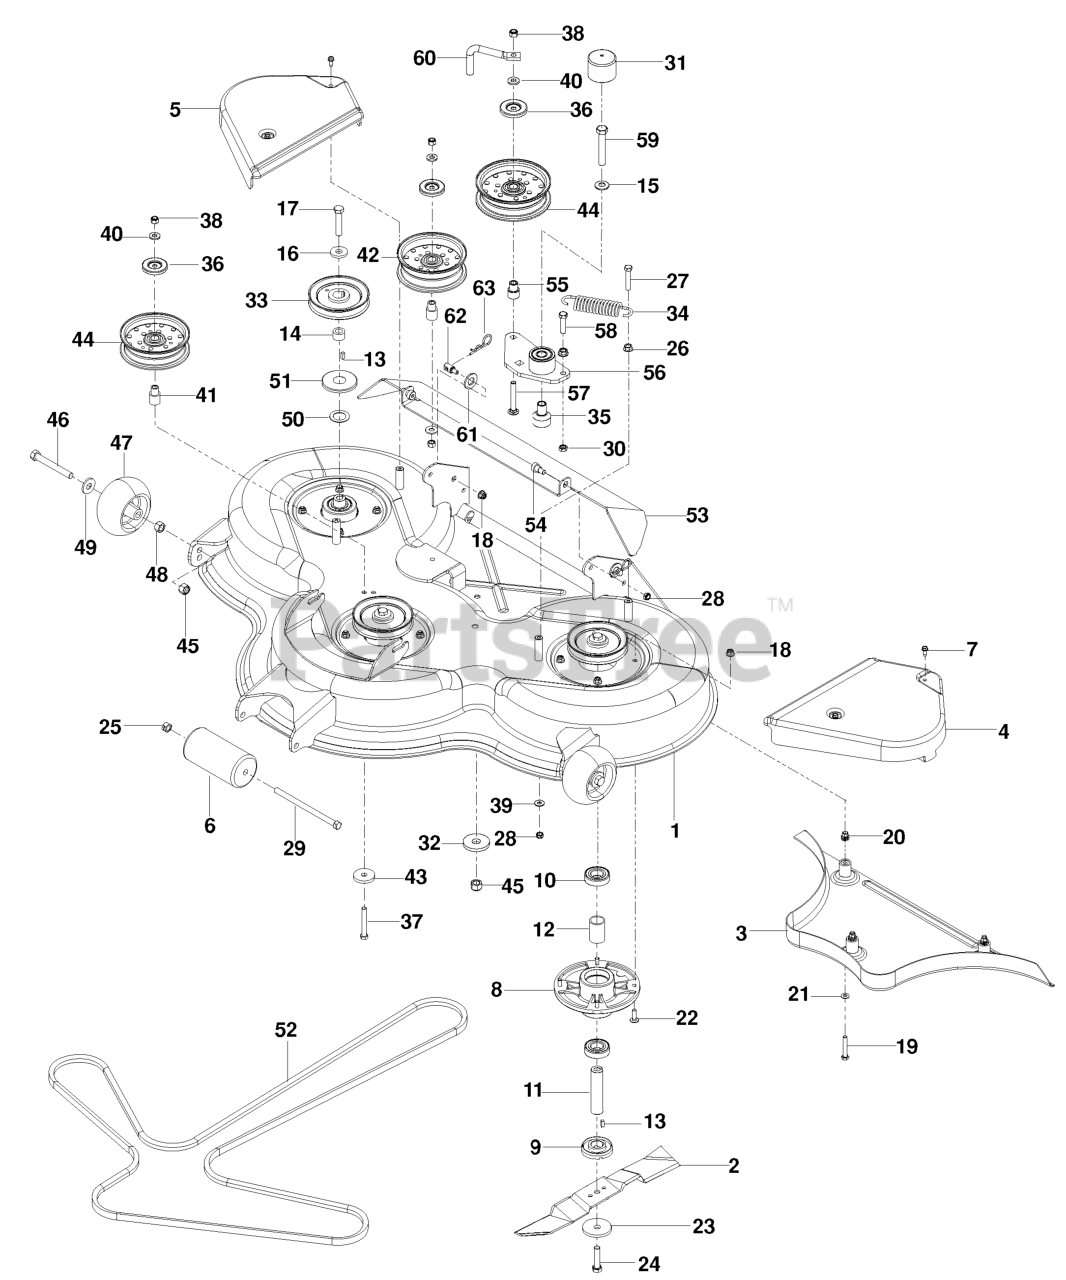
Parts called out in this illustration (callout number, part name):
1	DECK W/DECALS - EZ48 COMBI
2	BLADE
3	PLUG, MULCH, ORANGE
4	BELT SHIELD LT
5	BELT SHIELD RT
6	ROLLER
7	SCREW 1/4 X 5/8
8	BEARING HOUSING
9	BUSHING, BLADE
10	BALL BEARING
14	KEY RETAINER
15	CONTACT BELLSPR 1/2
16	WASHER-.533IDX1.37OD
17	HCS M12 X 1.75 X 60 GR5 ZD
18	5/16-18 NYLOC FLANGE NUT
19	HCS M8 X 1.25 X 50 GR8.8 ZD
21	FLAT WASHER 5/16 SAE
22	RHSNB 5/16C X 1
24	HCS M12 X 1.75 X 50 GR8.8 ZD
25	NUT 7/16C CENTERLOCK
26	NUT 3/8C WHIZ
27	HCS 3/8C X 2
28	NUT HEX 3/8-16 NYLON, THIN
29	HCS 7/16-14 X 7 GR5 ZD
30	NUT 3/8-16 HEX JAM
31	CAP, VINYL
32	WASHER, SUPPORT
33	PULLEY, 48
35	PIVOT, BEARING
36	DUST SHIELD
37	SCREW 3/8C X 2 3/4 HEX CAP
38	NUT 3/8-16 NYLOC
39	WASHER 3/8 FLAT
40	WASHER, 3/8 THICK
41	IDLER BUSHING
42	IDLER PULLEY (TALL)
43	SPINDLE WASHER
44	IDLER PULLEY
45	NUT 1/2-13 HEX NYLOC ZD
46	HCS 1/2-13 X 4 GR 5 ZD
47	GAUGE WHEEL
48	NUT 1/2 HEX JAM
49	WASH USS FLAT 1/2
50	WASHER-1.06IDX1.63ODX.06
51	BOTTOM DUST CAP
53	GUARD, DISCHARGE, BLK
54	SB 3/8-16 X 3/8 SKT HD ZD
55	BUSHING, IDLER
56	ARM-IDLER W/BRG
57	RHSNB 3/8-16 X 2.75
58	HCS 3/8-16 X 1-1/2
59	SCREW, 1/2C X 3 HEX CAP
60	BELT KEEPER 5"
61	WASHER 5/8 FLAT
62	STUD.FASTNER.W/ANTI-ROTATE
63	HAIRPIN #4
